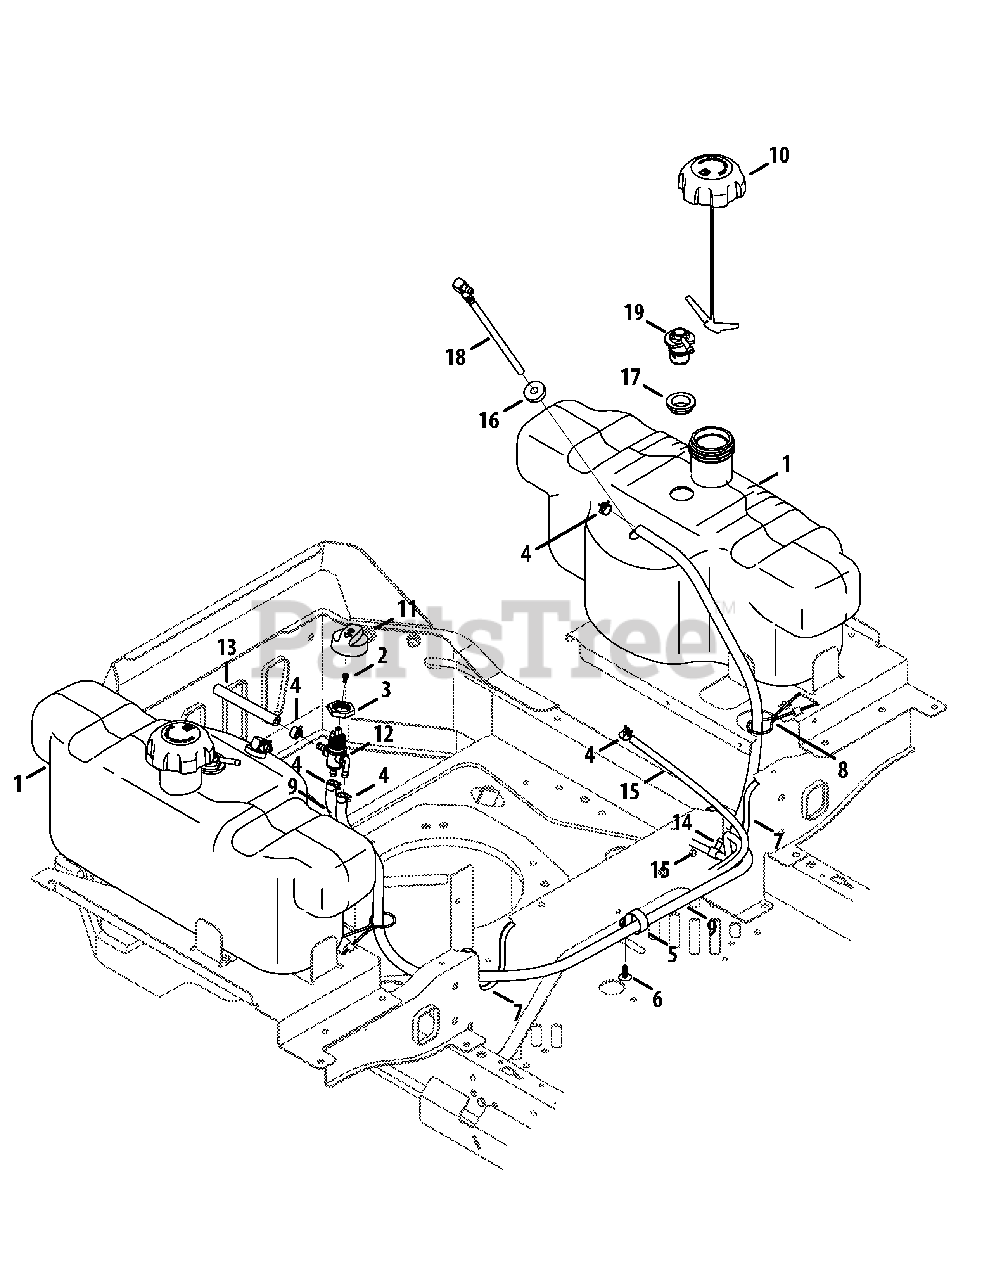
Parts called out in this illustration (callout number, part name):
1	Fuel Tank
2	Screw, M4-0.7 x 8mm
3	Nut, 3 Way Select
4	Hose Clamp, .490 Dia.
5	Hose Clamp, 1.0
6	Ratchet Clip, .250
7	Trim Strip
8	Tank Support Rod
9	Fuel Hose, Low Permeation, 1/4
10	Fuel Cap
11	Fuel Cap, 3 Way
12	Fuel Switch
13	Fuel Hose, Low Permeation, 1/4
14	Tee Fitting
16	Fuel Tank Bushing
17	Rubber Grommet
18	Fuel Pickup Fitting
19	Rollover Valve
